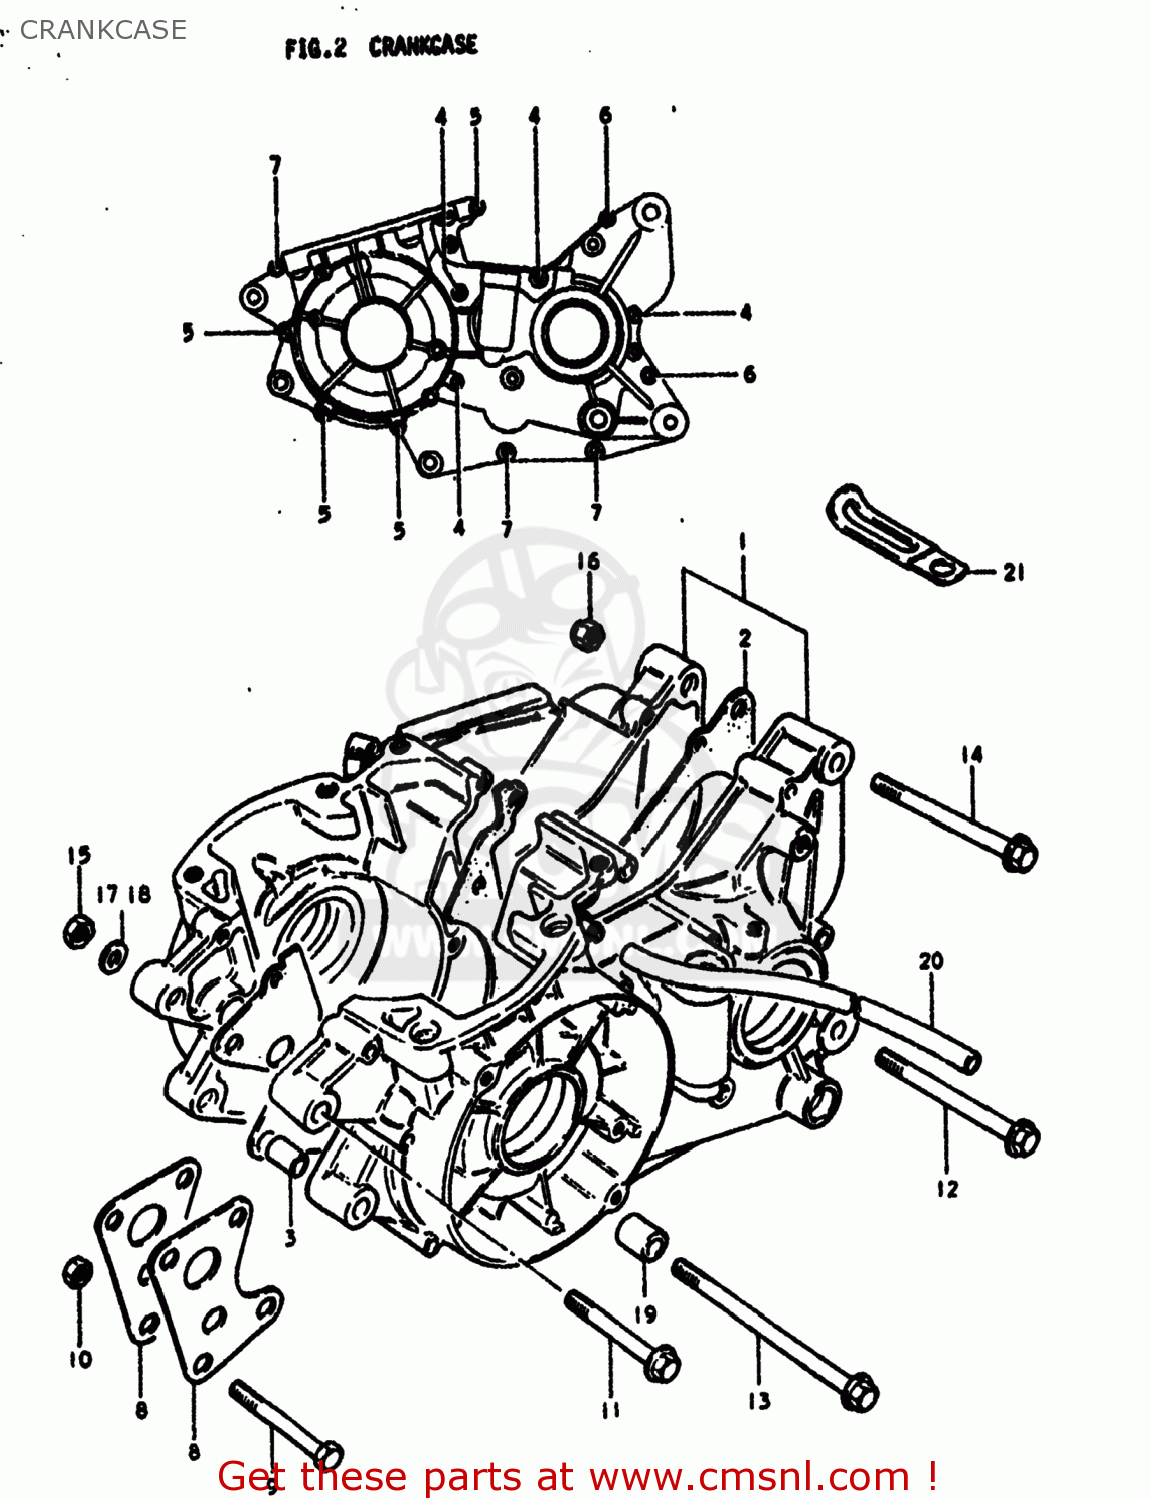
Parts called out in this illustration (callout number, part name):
1	CRANKCASE SET
2	GASKET,CRANKCASE (MCA)
3	PIN
4	SCREW 6X65
5	SCREW
6	SCREW
7	SCREW (6X35)
8	PLATE,ENGINE MOUNTING
9	BOLT(8X67)
10	NUT
11	BOLT(8X67)
12	BOLT
13	BOLT
14	BOLT
15	NUT
16	NUT
17	WASHER
18	WASHER
19	SPACER(8.6X16X26)
20	HOSE
21	CLAMP
